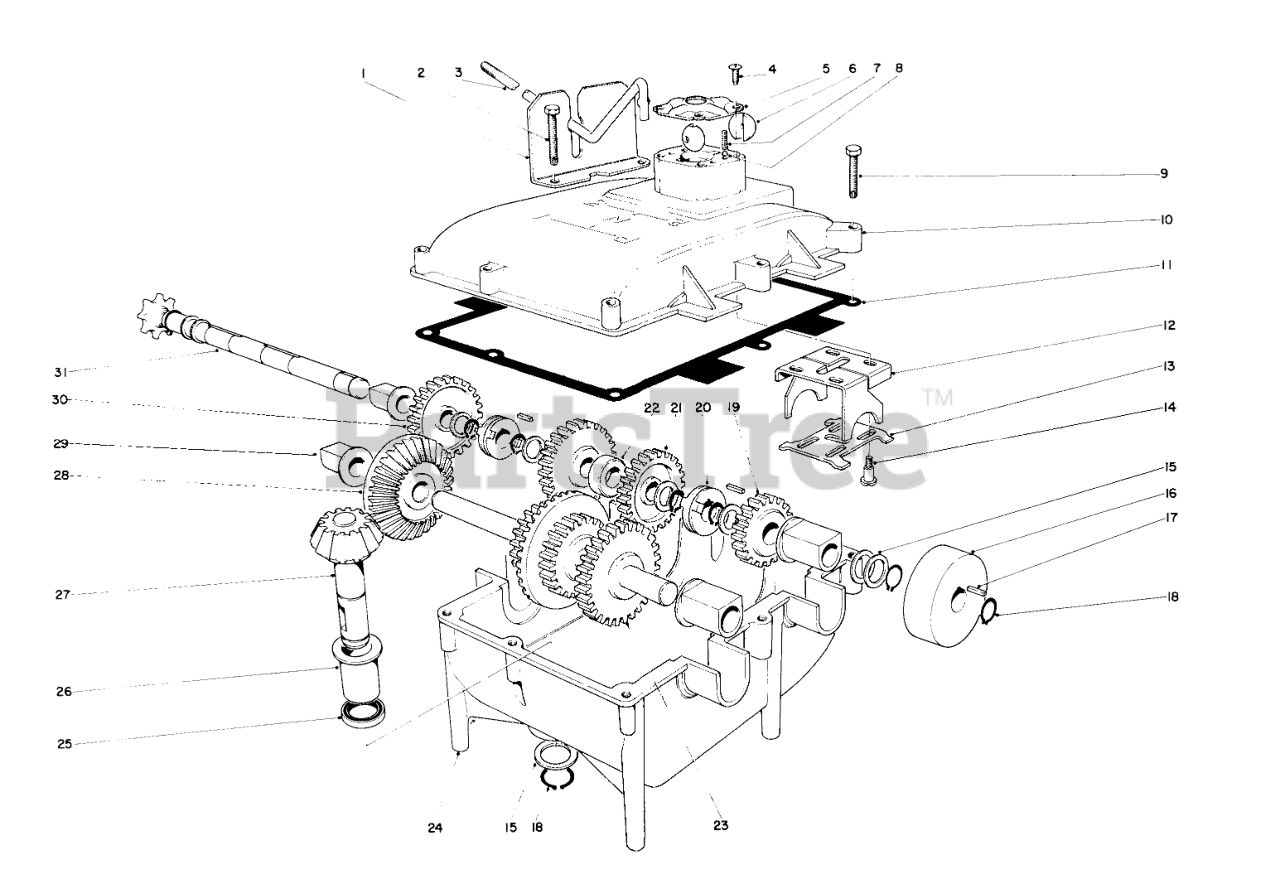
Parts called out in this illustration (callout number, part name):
1	Bracket Shift
3	Shift Rod
5	Cap Shift
6	Ball Shift Segment
7	Spring
8	Ball-Detent
10	Upper Gear Cover Housing
11	Gasket
12	Yoke Shift
13	Backing Plate
14	Screw Shoulder
15	Flat Washer
16	Brake Drum
17	Square Key
18	RING-SNAP, EXTERNAL
19	Gear-24 Teeth
20	Dog Driving
21	Gear-30 Teeth
22	Spacer
23	Assembly-Drive Shaft
24	Housing Gear
25	Grease Seal
26	Bushing
27	Assembly-Pinion Shaft
28	Bevel Gear
29	Bearing
30	Gear 36 Tooth
31	Shaft Sprocket
